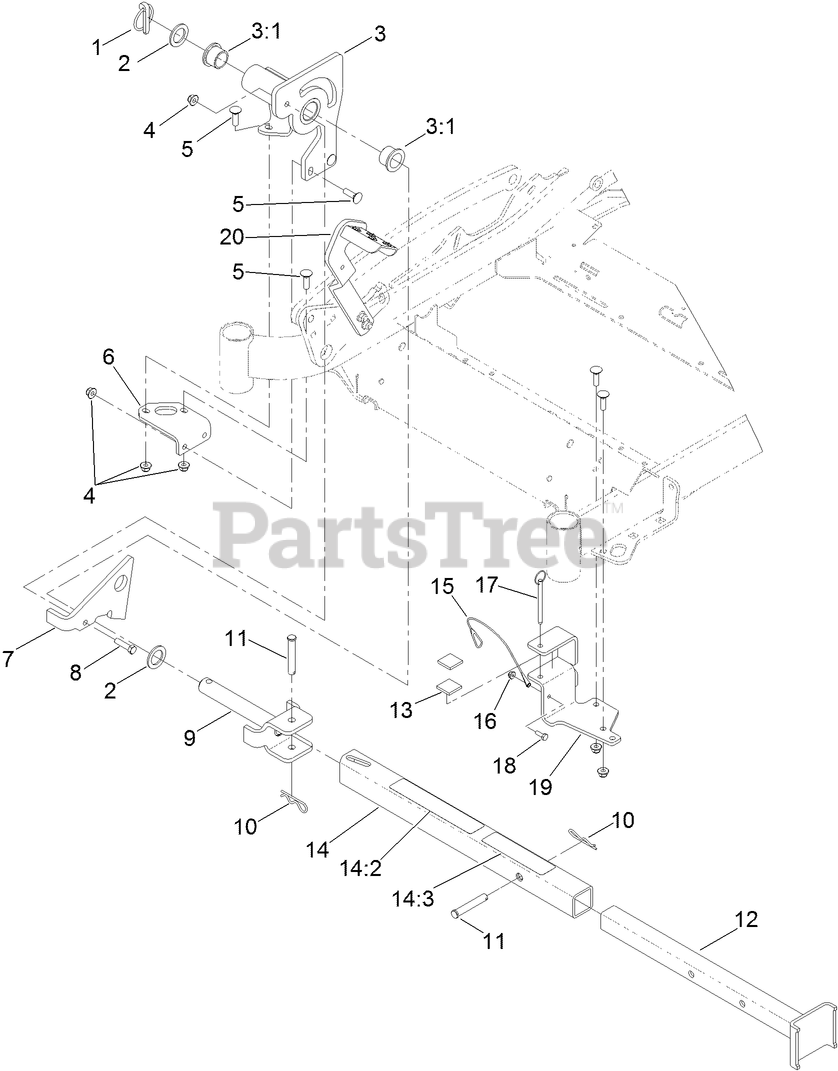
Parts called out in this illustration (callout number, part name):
1	PIN-LYNCH
2	WASHER-THRUST
3	Z STAND PIVOT ASM
3:1	BUSHING
4	NUT-HF, NI
5	BOLT-CARR
6	BRACKET-MOUNT, PIVOT
7	BRACKET-LATCH
8	SCREW-HH
9	PIN-PIVOT
10	PIN-HAIR
11	PIN-CLEVIS
12	TUBE-INNER
13	CUSHION-RUBBER
14	OUTER TUBE ASM
14:2	DECAL-Z STAND
14:3	DECAL-WARNING
15	LANYARD-NYLON
16	NUT-HF
17	PIN-HITCH, COTTERLESS
18	SCREW-HH
19	CRADLE-Z STAND
20	LEVER-FOOT
